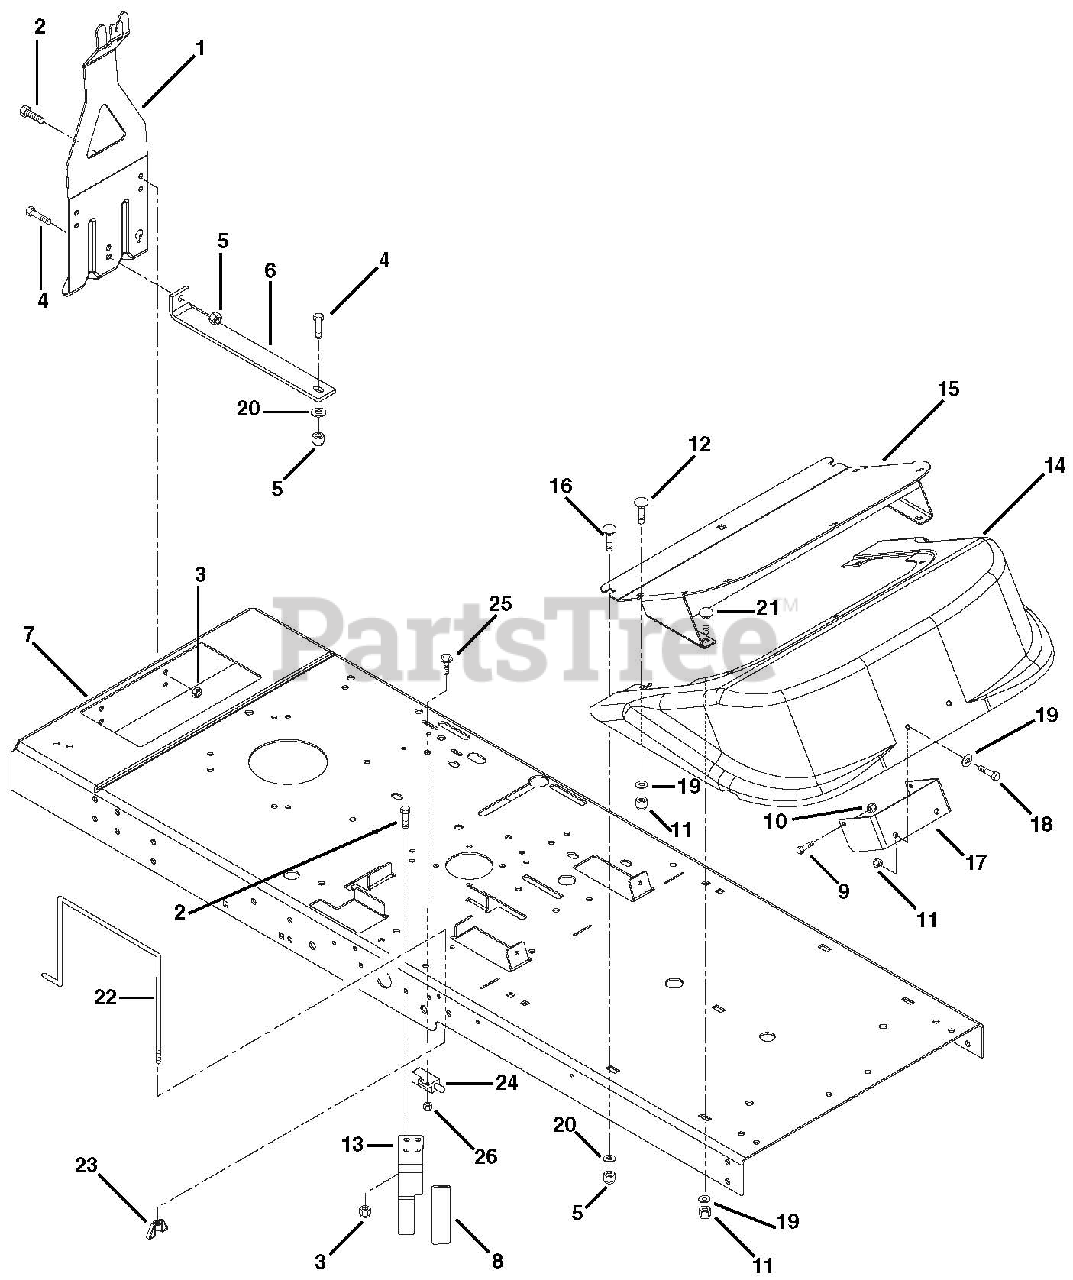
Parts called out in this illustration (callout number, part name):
1	HITCH, TRAILER
2	@BLT-HEX .31-18X.75 GR5 YWZC
3	@NUT-LK-CTR .31-18 YWZC
4	@BLT-HEX .38-16X1.00 GR5 YWZC
5	@NUT-LK-CTR .38-16 YWZC
9	@BLT-HEX .25-20X.75 GR5 YWZC
10	@NUT-LK-NYL .250-20 YWZC
10	@NUT-LK-CTR .25-20 YWZC
11	@NUT-LK-NYL .312-18 YWZC
12	@BLT-RHDSSQNK .31-18X.75 G5YZ
13	STOP - CLUTCH
14	SHROUD, FOOTREST
15	FOOTREST, WLDM'T
15	FOOTREST
16	@BLT-RDHDSQNK .38-16X.75 G5YZ
17	BRACKET, FOOTREST
17	BRACKET - FOOTREST
18	@BLT-HEX .31-18X.75 GR5 YWZC
18	@BLT-RDHDSQNK .25-20X.50 G5YZ
19	@WSHR-FL-STL.38X.875X.083 YWZC
20	@WSHR-FL-STL.406X.812X.065 YWZ
21	@BLT-RDHDSQNK .31-18X1.00 G5YZ
22	BATTERY ROD
23	NUT-LK WING .250-20 YWZC
24	SWITCH- SINGLE POLE N.O.
25	BLT-HEX FWH #10X.750 YWZC
26	@NUT-LK-NYL 10-24 W/INSRT YWZC
